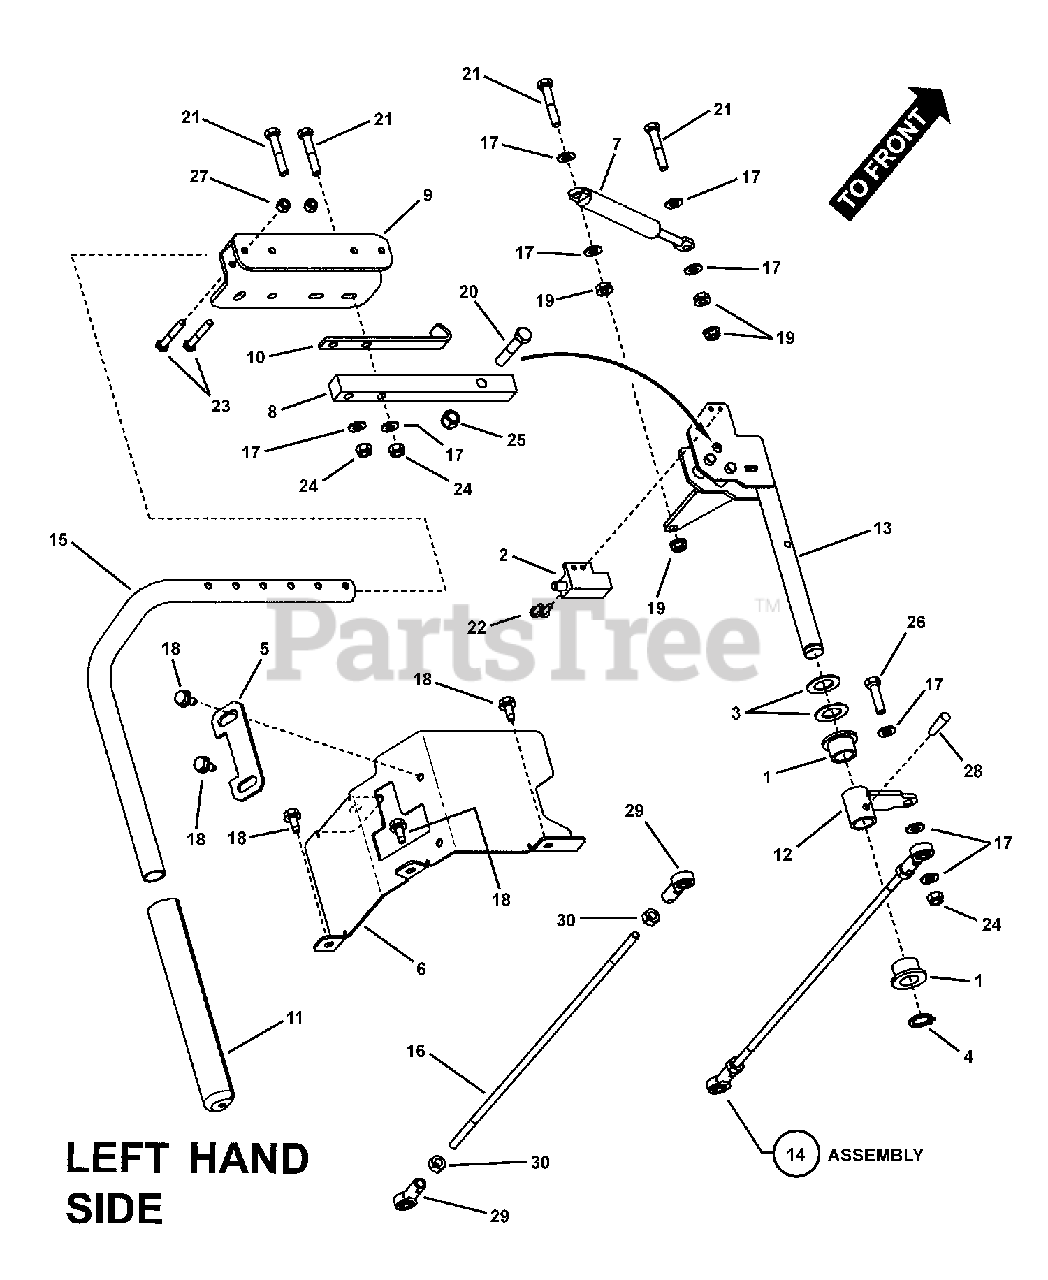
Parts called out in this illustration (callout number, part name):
1	BEARING, 3/4" I.D. Flange
2	SWITCH- DPDT (NC/NO)
3	WASHER, .77 I.D. Flat
4	RETAINING RING, 3/4" External
5	PLATE, Speed Control
6	COVER, Left Hand
7	DAMPENER, Hydraulic
8	TWIN BLOCK
9	BRACKET, Handle Adjustment
10	LEVER
11	GRIP, Twin Stick
12	WELDMENT, Stick Control
13	WELDMENT, Twin Stick
14	ASSEMBLY, Pump Control Linkage
15	HANDLEBAR, Twin Stick
16	LINKAGE, Pump Control (5/16-24 threads)
17	WASHER, 5/16" Flat
18	SCREW, 5/16-18 x 5/8" Hex Washer Self-Tap
19	NUT, 5/16-18 Hex Flange Lock
20	SCREW, 3/8-16 x 2" Hex Head Cap, GR 5
21	BOLT, 5/16-18 X 1-3/4 GD5 YZ
22	SCREW, #10-24 x 1/2" Hex Washer Self-Tap (Torx)
23	SCREW, 1/4-20 x 1-3/4" Hex Head Cap, GR 5
24	NUT, 5/16-18 HEX NYLON LOCK
25	NUT, 3/8-16 HEX NYLON LOCK
26	BOLT, 5/16-18 X 1-1/4 GD5 YZ
27	NUT, 1/4-20 HEX NYLON LOCK
28	GROOVE PIN, 1/4 x 1-1/4" long
29	BALL JOINT, Pump Control Linkage (5/16-24 thread)
30	NUT, 5/16-24 Hex, GR 5
